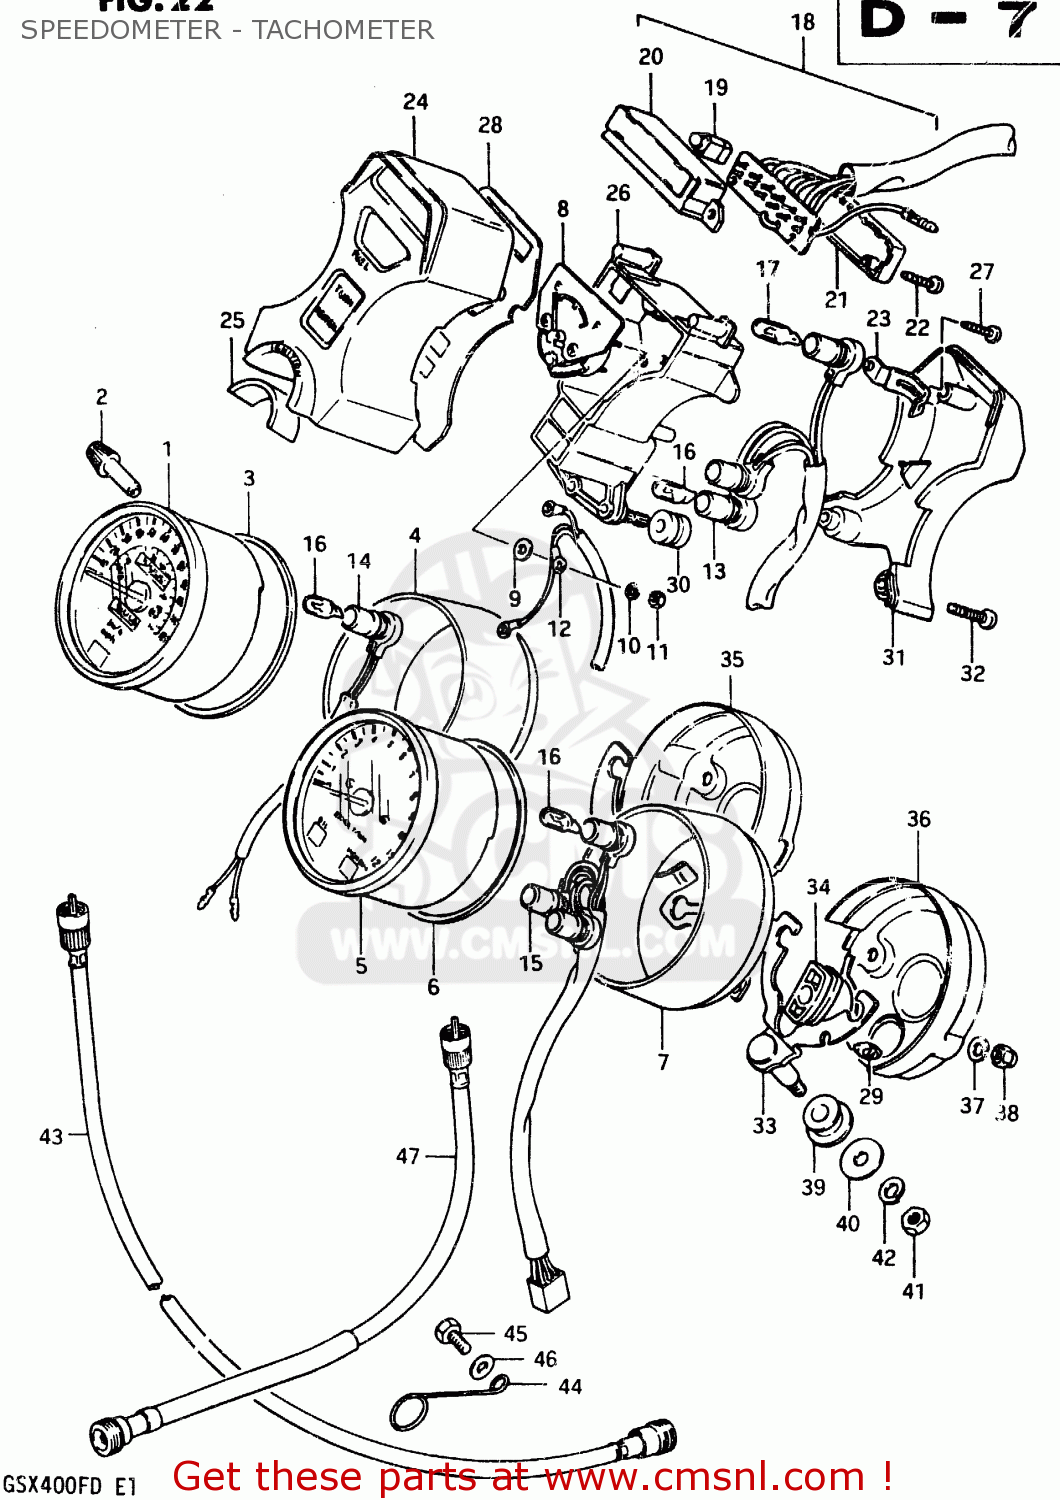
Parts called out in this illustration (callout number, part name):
1	SPEEDOMETER (KILO)
2	KNOB
3	CUSHION,SPEEDOMETER
4	COVER,SPEEDOMETER
5	TACHOMETER
6	CUSHION,SPEEDOMETER
7	COVER,TACHOMETER
8	METER,FUEL
9	WASHER,FUEL METER
10	LOCK WASHER
11	NUT 3MM
12	LEAD WIRE,FUEL METER
13	SOCKET,PILOT CASE
14	SOCKET,METER
15	SOCKET,TACHOMETER
16	BULB(12V3.4W,T10)
17	BULB(12V1.7W,T10,WB121)
18	INDICATOR, GEAR POSITION
19	BULB(14V1.12W)
20	CASE,GEAR INDICATOR
21	COVER,LWR
22	SCREW,GEAR INDICATOR
23	CLAMP,CORD
24	CASE,PILOT BOX
25	SEAL,IGNITION SWITCH
26	CASE,PILOT BOX,INNER
27	SCREW,INDICATOR
28	PLATE,PILOT BOX
29	CUSHION,METER
30	CUSHION,PILOT BOX
31	COVER,PILOT BOX,UNDER
32	SCREW
33	BRACKET
34	CUSHION,METER
35	COVER,METER,UNDER
36	PLATE,TACHOMETER UNDER
37	WASHER
38	NUT
39	CUSHION,METER BRACKET
40	WASHER (8.5X29X1.6)
41	NUT
42	LOCK WASHER
43	CABLE ASSEMBLY,SPEEDOMETER
44	CLAMP,SPEEDOMETER CABLE
45	BOLT, UPPER
46	WASHER
47	CABLE ASSEMBLY,TACHOMETER
